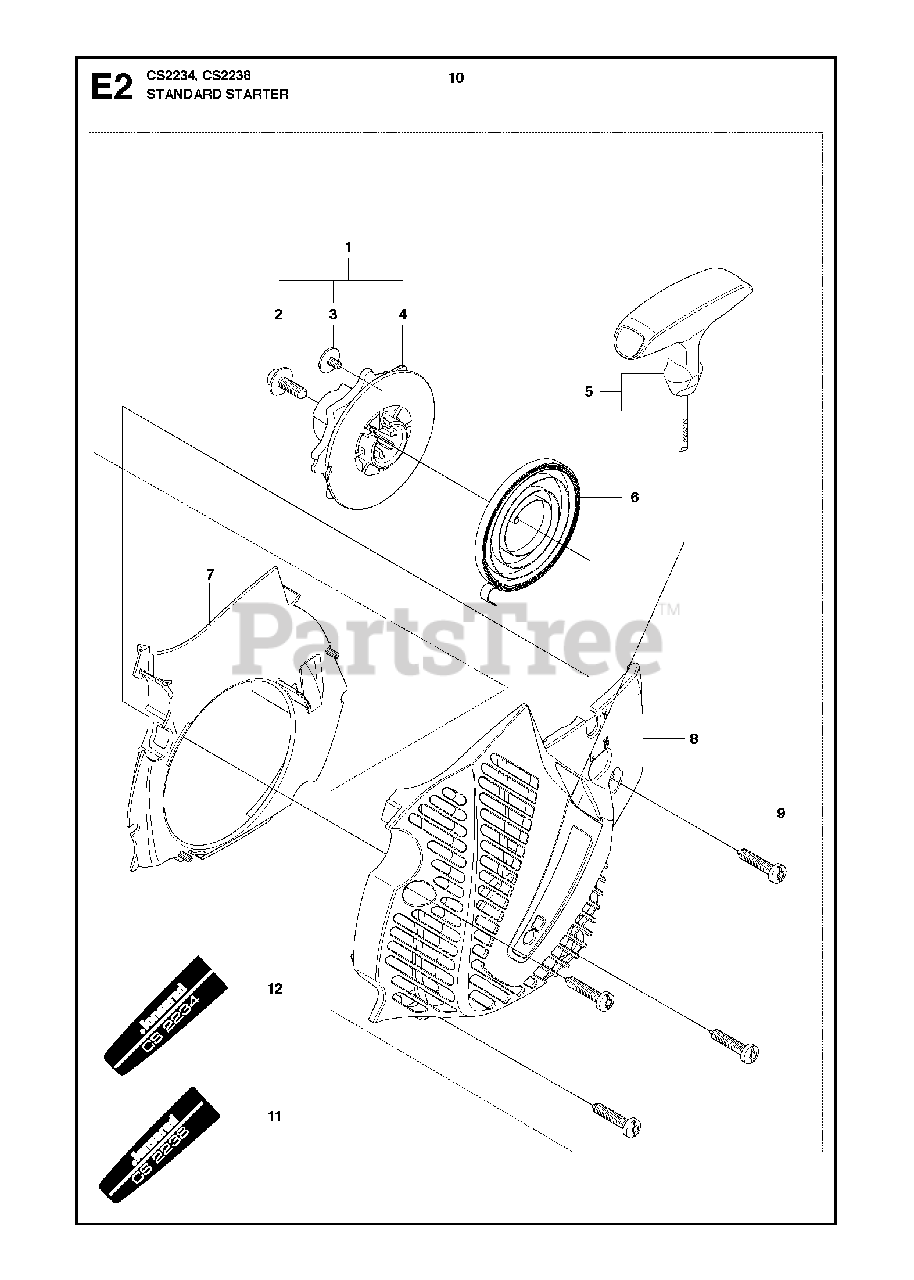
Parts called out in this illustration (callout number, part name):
1	KIT, STD STARTER
2	SCREW
3	SCREW
4	STARTER PULLEY
6	SPRING STARTER
9	SCREW M5.38-14X22.225MM
